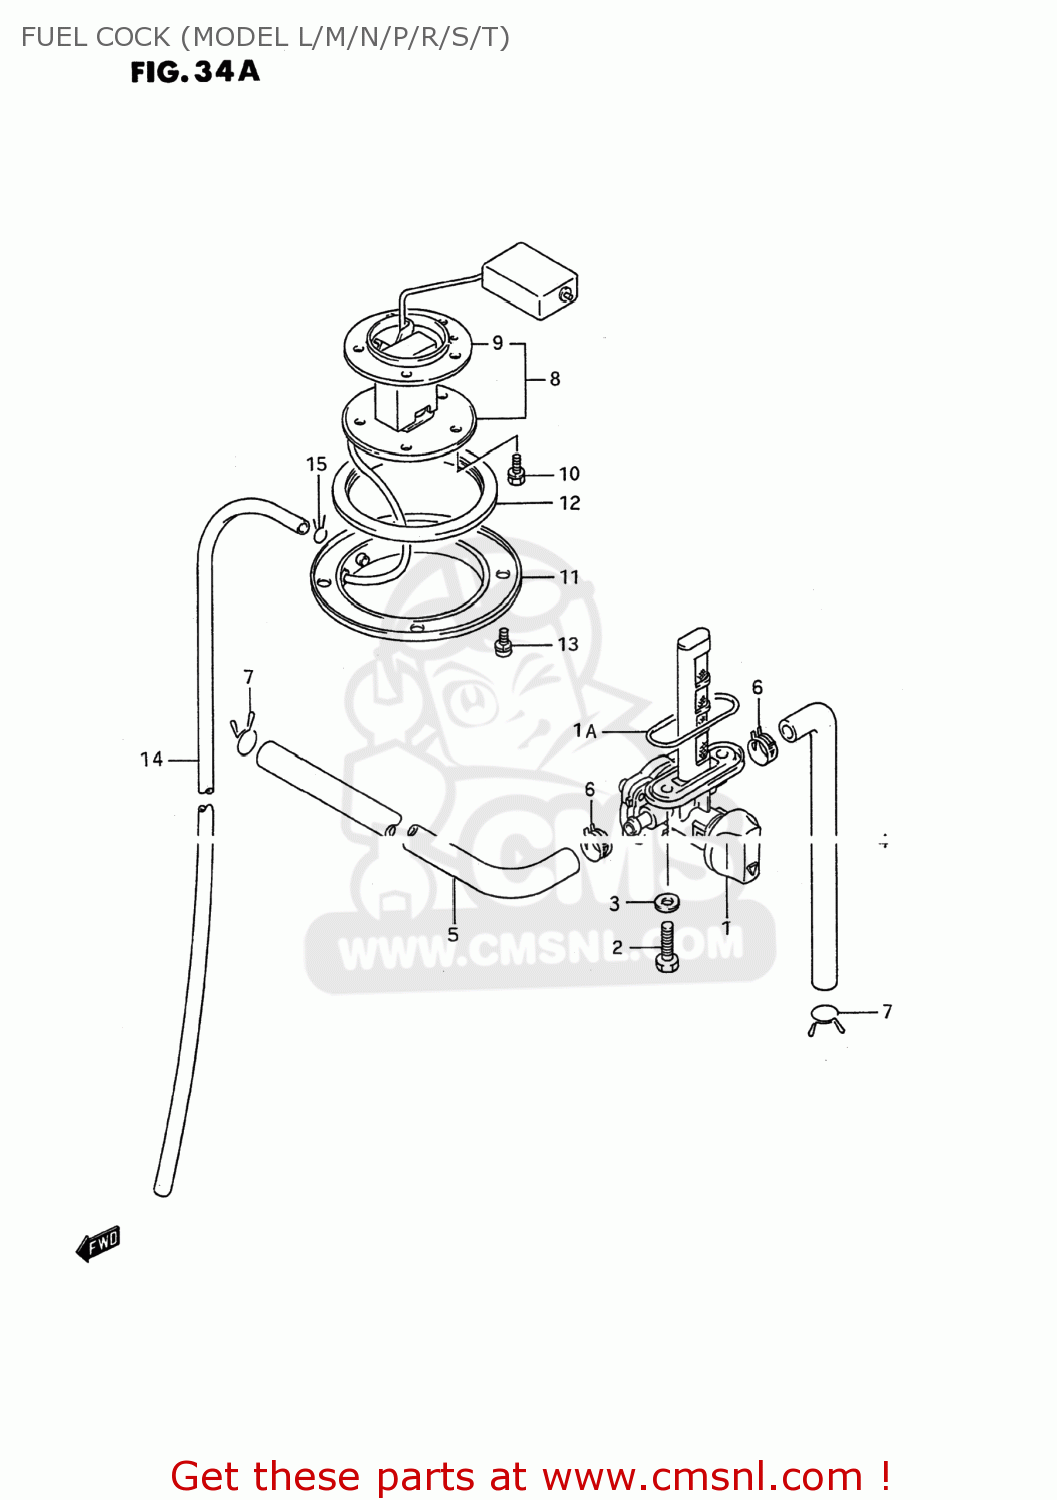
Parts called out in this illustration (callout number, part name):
1	COCK ASSY,FUEL
1A	O RING
2	BOLT(6X20)
3	GASKET(6.4X11.5X0.8) (NAS)
4	HOSE (7X12X150)
5	HOSE (7X12X330)
6	CLIP
7	CLIP
8	GAUGE ASSY,FUEL LEVEL SENDER
9	GASKET,FUEL LEVEL GAUGE (NAS)
10	BOLT
11	PLATE,FUEL DRAIN
12	GASKET,FUEL DRAIN PLATE (NAS)
13	BOLT
14	HOSE(5X8.2X2000)
15	CLIP
